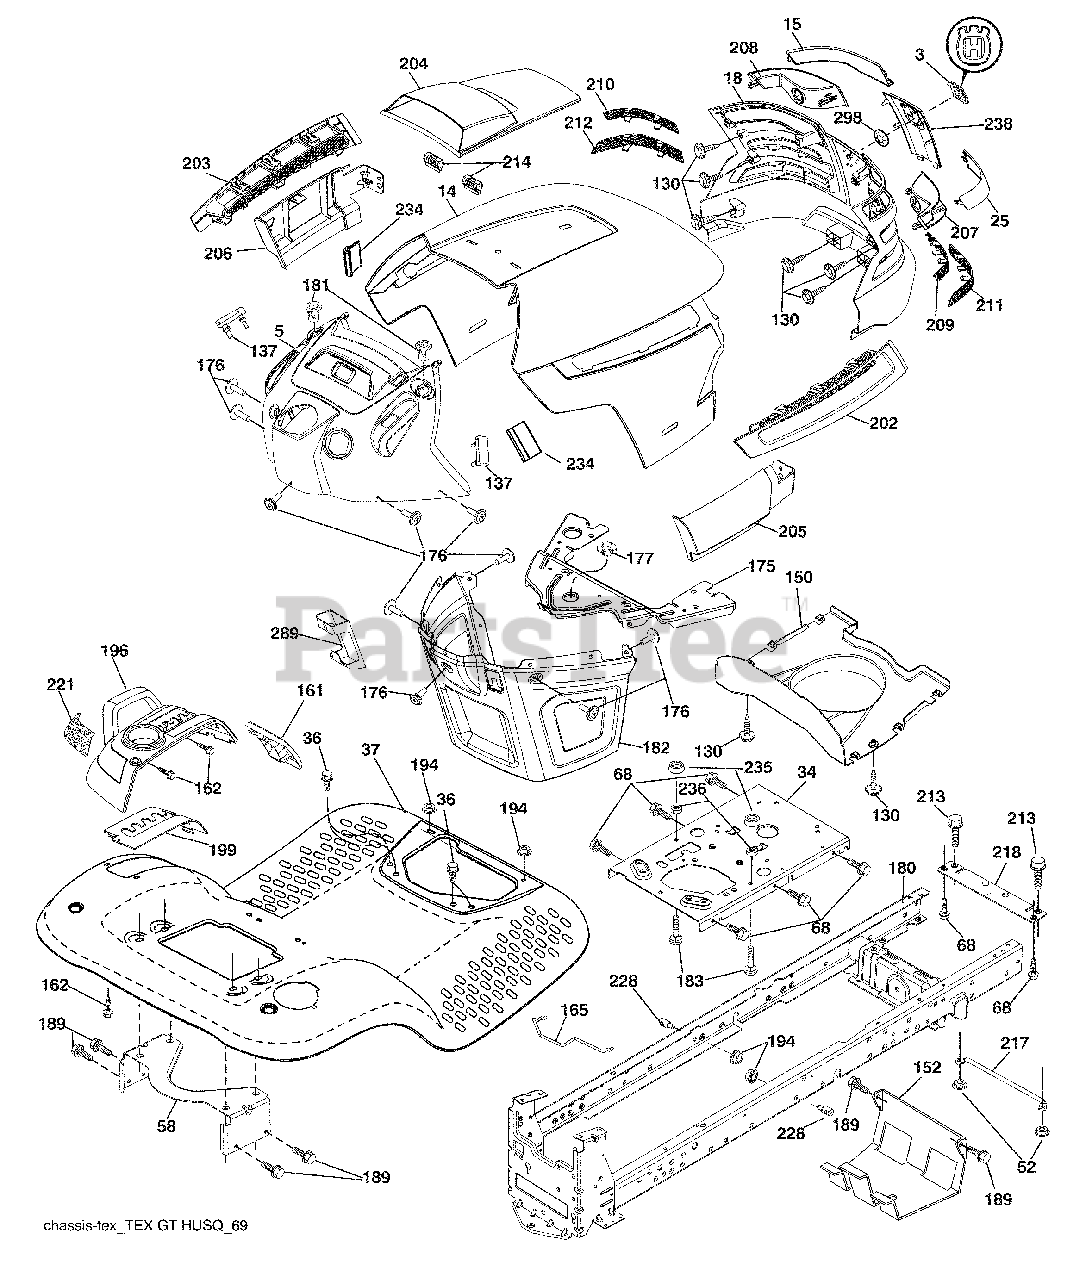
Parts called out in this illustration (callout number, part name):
3	Logo
14	Hood
34	Plate Engine
36	Screw 5/16-18 x 3/4
37	Fender
52	Nut Crown Lock 5/16-18
58	Bracket Fender
68	Screw 5/16-18 x 1/2
130	Screw #10 x 0.750 BOS Thread
137	Bumper Dash
150	Duct Heat Hood
152	Shield Browning/Debris\
161	Console Fuel Window
162	Screw Hex Wsh Hi-Lo 1/4 x 1/2
165	Bracket Support Tank
175	Crossmember
176	Screw 10-24 x 5/8 Wshd Qdrx
177	Bushing Steering
180	Chassis
181	Bushing MMT Fender
182	Dash Lower
183	Bolt 5/16-18 x 1-1/4
189	Screw 5/16-18 x 3/4
194	Nut Lock 5/16-18
196	Console Asm. Deck Lift
199	Plate Deck Lift
202	Vent Side Hood RH
203	Vent Side Hood LH
204	Vent Asm Hood Top
205	Skirt Hood Side RH
206	Skirt Hood Side LH
209	Insert Hex Top RH
210	Insert Hex Top LH
211	Insert Hex Bottom RH
212	Insert Hex Bottom LH
213	Bolt Hex Hd 5/16-18 unc x 3/4
214	Clip Retainer
218	Hood Stop X Piece
221	Reflector LH
228	Stud Fastener
234	Bumper Hood
235	Spacer Fender
236	Nut Center Lock 5/16-18 unc
289	Plug Cruise/Phone
